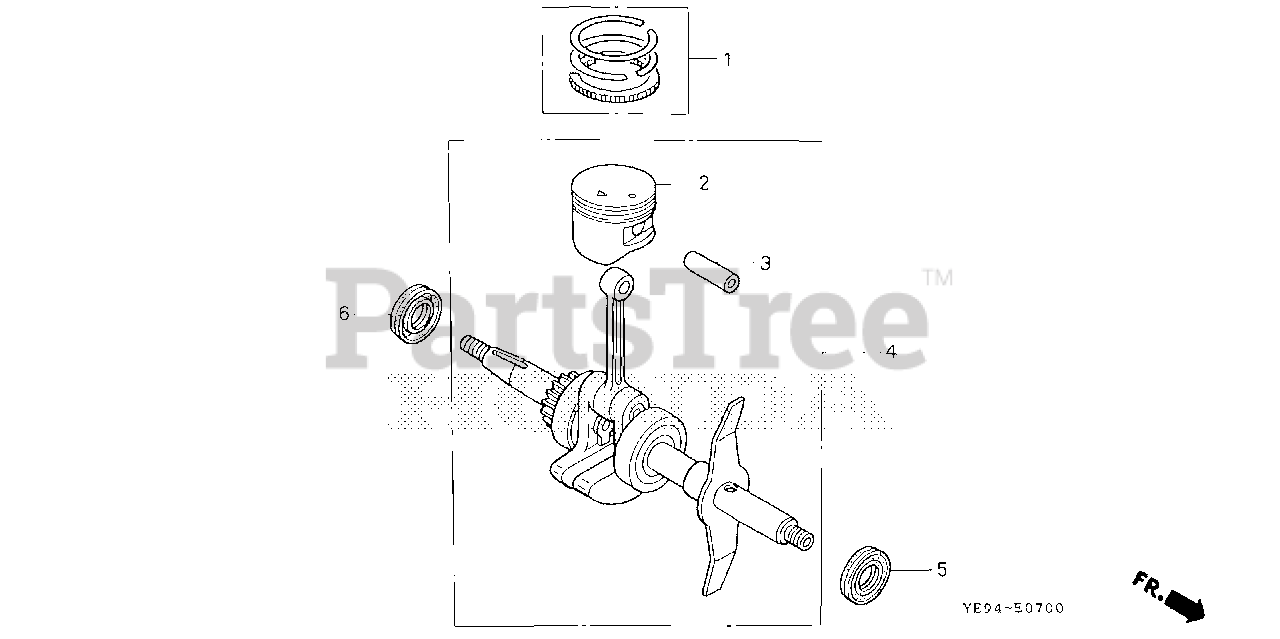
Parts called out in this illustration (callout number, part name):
1	RING SET, PISTON (RIKEN)
2	PISTON
3	PIN, PISTON
4	CRANKSHAFT
5	OIL SEAL (12X25X6)
6	OIL SEAL (15X25X6)
